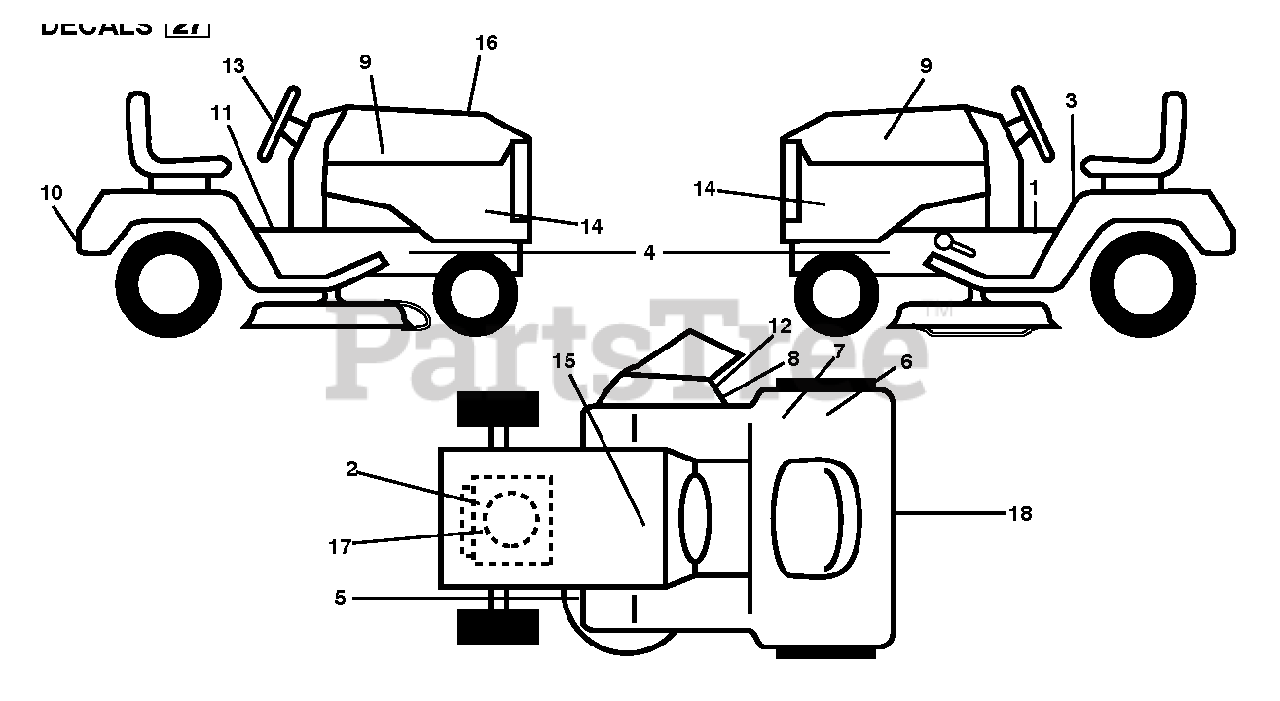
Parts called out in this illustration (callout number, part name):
1	DECAL PARK BRAKE
5	DECAL V BELT SCHEMATIC
7	DECAL.80 DBA.AUSTRALIA
8	DECAL, DEFLECT WARNING
12	DECAL.INTERNATIONL.CUTFINGER
15	DECAL BTRY SYMBOLS
